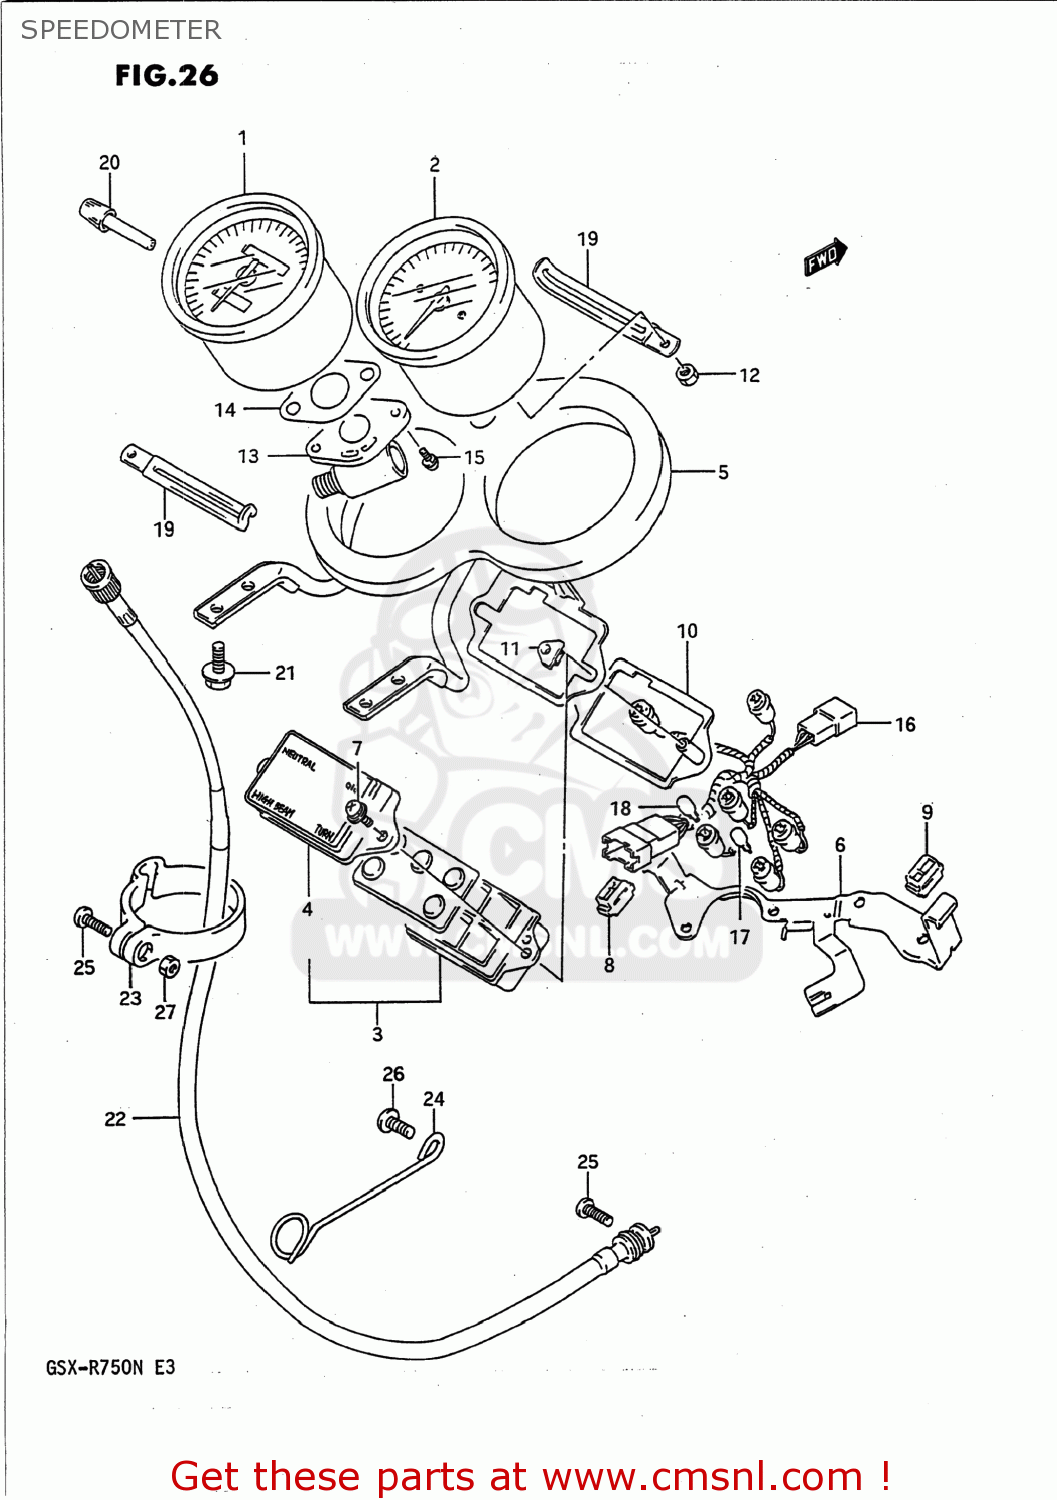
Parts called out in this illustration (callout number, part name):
1	SPEEDOMETER ASSEMBLY
2	TACHOMETER
3	BOX ASSEMBLY,PILOT LAMP
4	LENS,BOX
5	PLATE,SET
6	BRACKET
7	SCREW
8	DAMPER,LEFT
9	CUSHION
10	PLATE,SETTING
11	DAMPER
12	NUT
13	GEAR BOX
14	GASKET,METER GEAR BOX (NAS)
15	SCREW
16	SOCKET,METER
17	BULB(12V3W,T6.5)
18	BULB(12V1.7W,T6.5)
19	CLAMP
20	KNOB,TRIP
21	BOLT 6X12
22	CABLE ASSEMBLY,SPEEDOMETER
23	CLAMP,SPEEDOMETER CABLE
24	GUIDE,SPEEDOMETER CABLE NO.3
25	SCREW
26	SCREW
27	NUT 5MM
